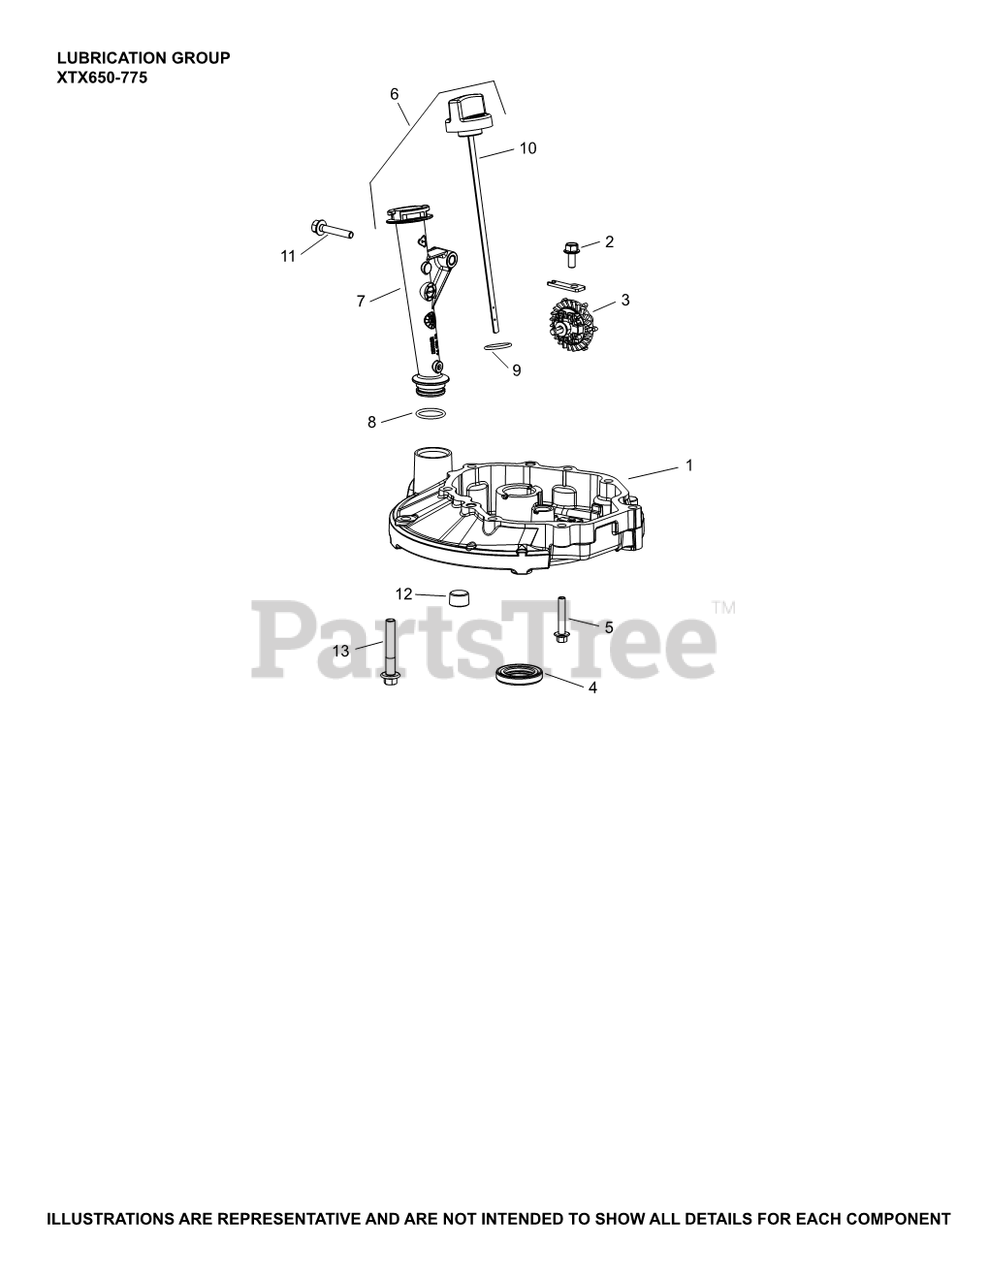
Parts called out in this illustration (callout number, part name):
1	KIT, OIL PAN
2	SCREW, HEX FLANGE (M6)-USE 25 086 433-S
3	GEAR ASSEMBLY, GOVERNOR
3	GOVERNOR ASSEMBLY USE 17 310 08-S
6	"PUSH-IN" DIPSTICK AND TUBE ASSEMBLY USE 14 123 20-S
7	TUBE ASSEMBLY, OIL FILL
8	O-RING, OIL FILL TUBE
9	O-RING (CAP)
10	CAP, DIPSTICK ASSEMBLY
11	SCREW, HEX FLANGE (M6) - USE 25 086 435-S
12	PLUG, PIPE (W/SEALANT)
13	SCREW, HEX FLANGE (M8) USE 25 086 456-S
